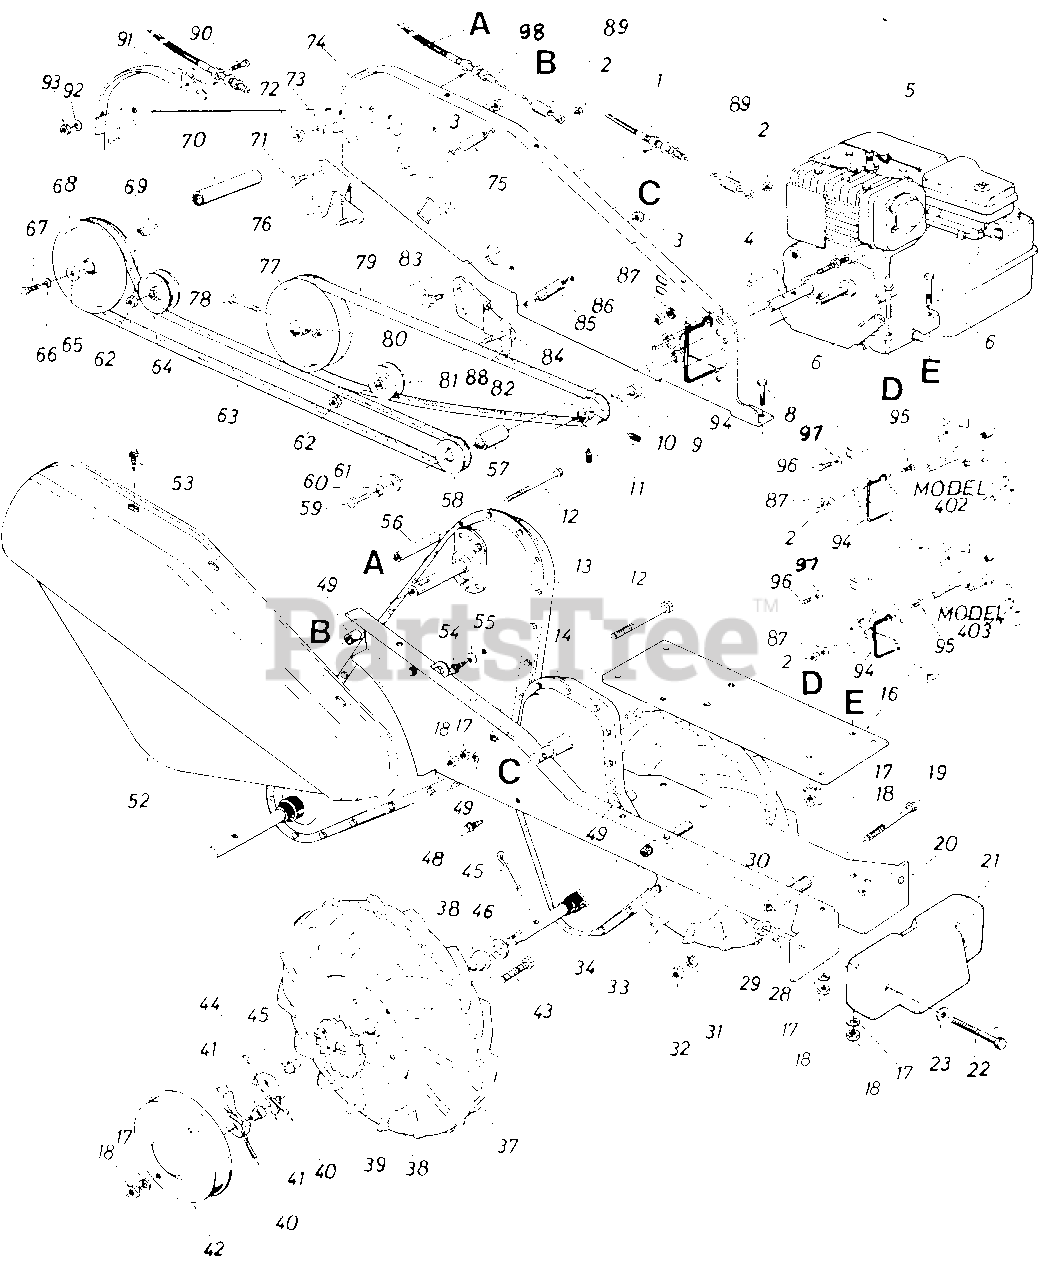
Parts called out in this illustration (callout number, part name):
1	Clutch Control Cable
2	Hex Cent. L-Nut 1/4-20 Thd.
3	Hex Cent. L-Nut 3/8-16 Thd.
4	Sq. Key 3/16" Dia. x .75
5	Engine
6	Hex Bolt 5/16-18 x 1.50" Lg.
8	Hex Bolt 5/16-18 x .75" Lg.
9	Spacer .51" I.D. x 314" O.D. x .39" Lg.
10	Hi-Pro Key #5 Woodruff
11	Set Scr. 1/4-28 x .25" Lg.
12	Hex Bolt 5/16-18 x 3.0" Lg.
18	Hex Nut 5/16-18 Thd.
19	Hex Bolt 3/8-24 x 3.0" Lg.*
22	Hex Bolt 1/2-13 x 4.0" Lg.
23	Fl-Wash. 1/2" I.D. x 1.0" O.D.
28	L-Wash. 1/2" I.D.
29	Hex Nut 1/2-13 Thd.
30	Spacer 3/8" I.D. x 5/8" O.D. x 2.18" Lg.
31	L-Wash. 3/8" I.D.
32	Hex Nut 3/8-24 Thd.
33	Comp. Wheel Ass'y.-L.H.
38	Flange Brg. 718" I.D. x 1.12" Lg.
39	Ratchet Wheel
40	Nylon Spring
41	Pawl .44" I.D.
42	Wheel Cover
43	Hex Bolt 5/16-18 x 1.25" Lg.
44	Special Hex Nut 5/16-24 Thd.
45	Cotter Pin 118" Dia. x 1.25"
46	Fl-Wash. 718" I.D. x 1-3/8" O.D. x .06
48	Hex Wash. Self-Tap Scr. 5/16-24 x .50" Lg.
49	Spacer 5116" I.D. x 16 Ga. x.96" Lg.
52	Belt Cover
53	Hex Wash. S-Tap Scr. 1/4-20 x.50" Lg.
54	Hex Wash. S-Tap Scr. 1/4-20 x 3/8" Lg.
55	Bell-Wash. 1/4" I.D.
56	Spacer 3/8" I.D. x 1/2" O.D. x 2.0" Lg.
57	Spacer 314" I.D. x 1.12" O.D. x 1.56" Lg.
58	1/2" "V"-4L Pulley 314" I.D. x 2.59" O.D.
59	Hex Bolt 5/16-24 x 1.0" Lg.
60	L-Wash. 5/16" I.D.
61	Fl-Wash. 5/16" I.D. x 1.25" O.D.
62	Hex L-Nut 3/8-24 Thd.
63	"V"-Belt 1/2" x 54" Lg.
64	Fl-Idler Pulley 3.75" O.D. x 3/8" I.D.
65	Fl-Wash. .25" I.D. x .93" O.D. x .1 20
66	L-Wash. 1/4" I.D.
67	Hex Bolt 1/4-28 x .75" Lg.
68	Split Pulley 6" Dia. x 5/8" I.D.
69	Hi-Pro Key
70	Spacer
71	Shld. Bolt 1/2" Dia. x .210" Lg.
72	Hex Nut 5/16-18 Thd.
73	L-Wash. 5/16" I.D.
74	Side Plate Ass'y.
75	Ext. Spring .50" O.D. x 1.55" Lg.
76	Idler Bracket Ass'y.-Tines
77	Pulley 6" Dia. x 5/8" I.D.
78	Hex Bolt 1/4-28 x 1.50" Lg.
79	"V"-Belt 1/2" x 43" Lg.
80	Hex Cent. L-Nut 1/4-28 Thd.
81	"V"-Idler Pulley 2-5/8" O.D.
82	1/2 V-Pulley 2 1/4 O.D. x 50n 1 D
83	Shld. Bolt 1/2" Dia. x .160" Lg.
84	Id ler Bracket Ass'y-Wheels
85	Ext. Spring 50" O.D. x 1.55" Lg.
86	Hex Nut 1/4-20 Thd.
87	Bell-Wash. 1/4" I.D.
88	Belt KeeperAss'y.
89	Ext. Spring
90	Hex Bolt 5/16-18 x 75"
91	Clutch Cable Brkt.
92	Lock Washer 5/16" I.D.
93	Hex Nut 5/16-18 Thd.
94	Belt Keeper
95	Hex Bolt 1/4-20 x 1.25" Lg.
96	Hex Bolt 5/16-24 x .62" Lg.
97	Bell-Wash. 5/16" I.D.
98	Tine Control Cable
